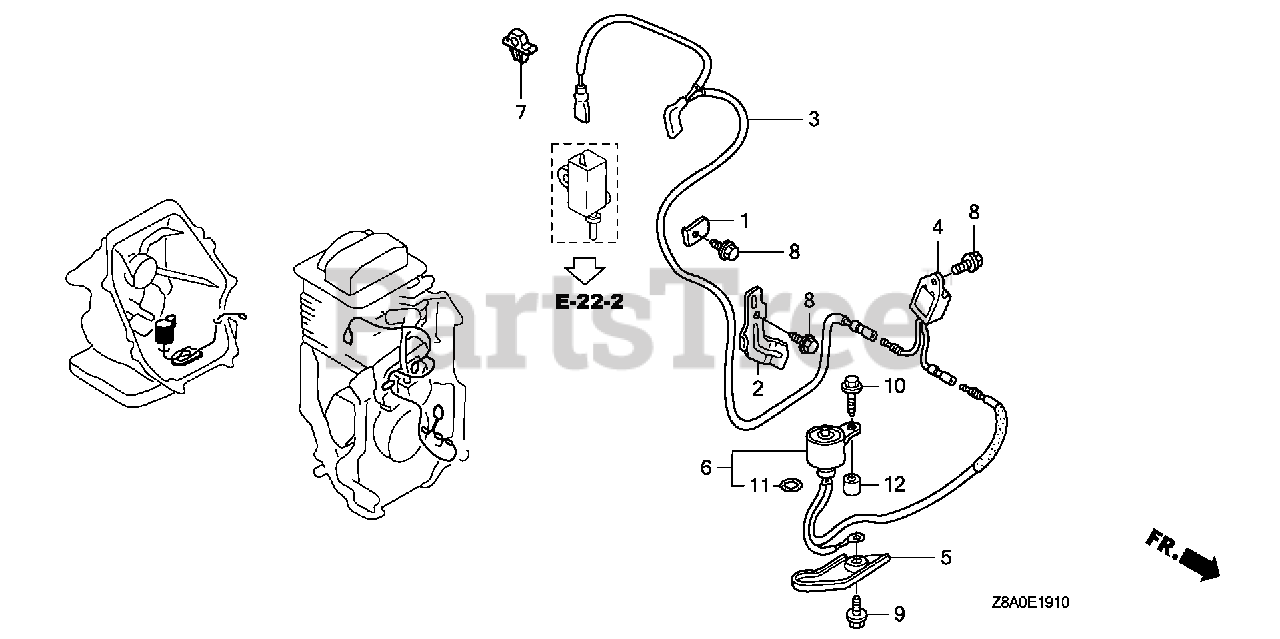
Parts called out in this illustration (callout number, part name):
1	CLAMP, STOP SWITCH WIRE
2	CLAMP, WIRE
3	WIRE, STOP SWITCH
4	ALERT UNIT, OIL
5	PROTECTOR, SWITCH
6	SWITCH, OIL LEVEL
7	HOLDER, STOP SWITCH WIRE Use up to Engine SN 2056819.
7	HOLDER, WIRE (FASTEX)
8	BOLT, FLANGE (6X12) (CT200)
9	BOLT, FLANGE (6X14)
10	BOLT, FLANGE (6X28) (CT200) Use up to Engine SN 1530314.
11	O-RING (11.8X2.4)
12	COLLAR (6.6X13.8X14.5)
